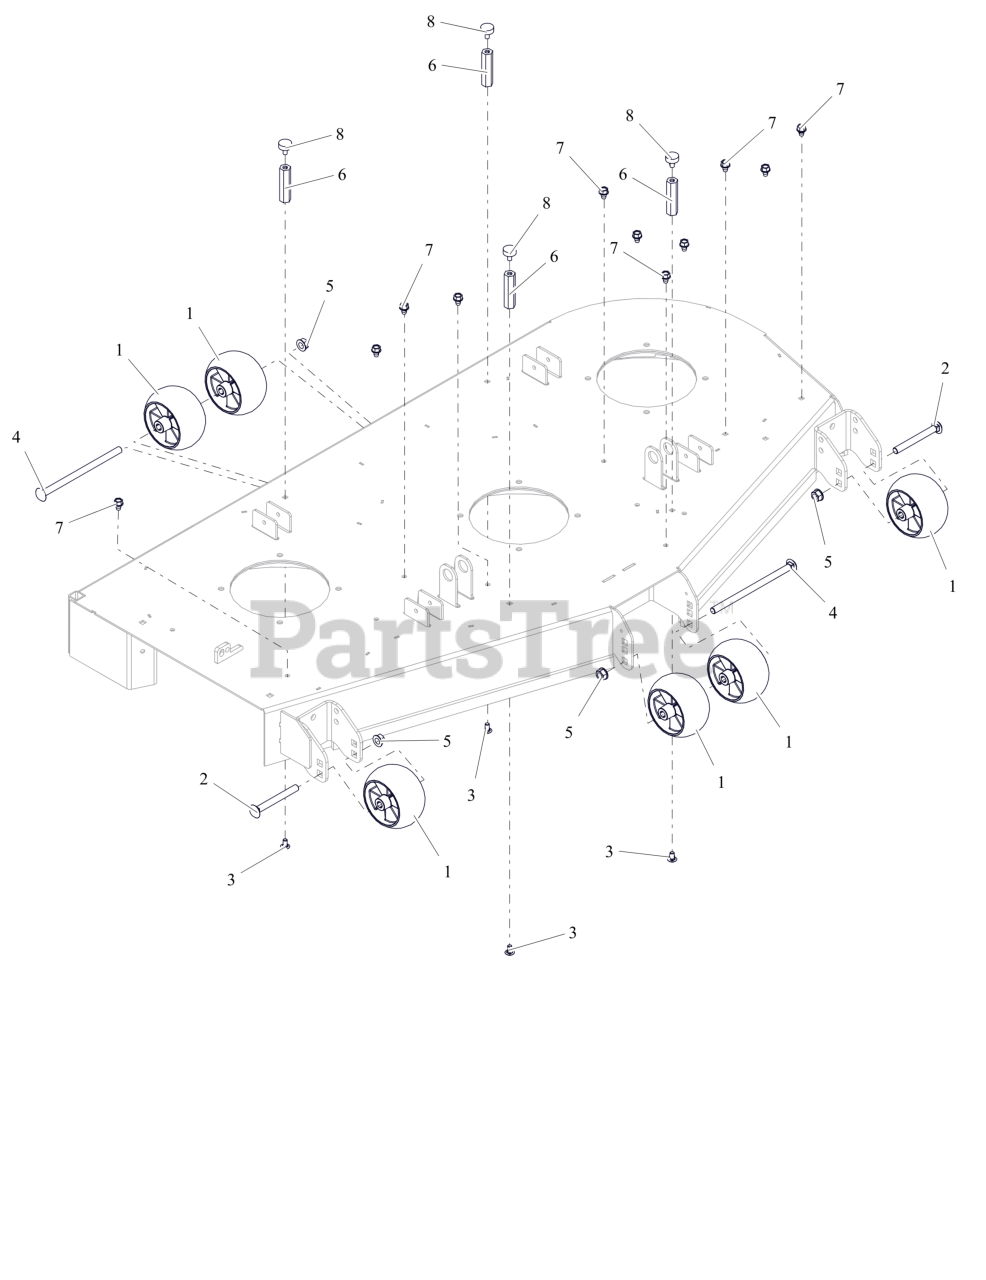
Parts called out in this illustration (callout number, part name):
1	WHEEL, ANTI SCALP - 5X3 CTR W/RIBS
2	BLT,RHSN .50-13X4.50 G5 ZCC
3	BLT,RHSSN.31-18X.625 G5 ZCCP30
4	BTL,RHSN .500-13 X 8.5S G5 ZCC
5	NUT-LK-CTR-FLG .500-13 GG ZCC
6	NUT, COUPLING .31-18 X 3.00
7	SCR,TAP .375-16X.50 HWH TR ZCC
8	BUMPER, RUBBER
